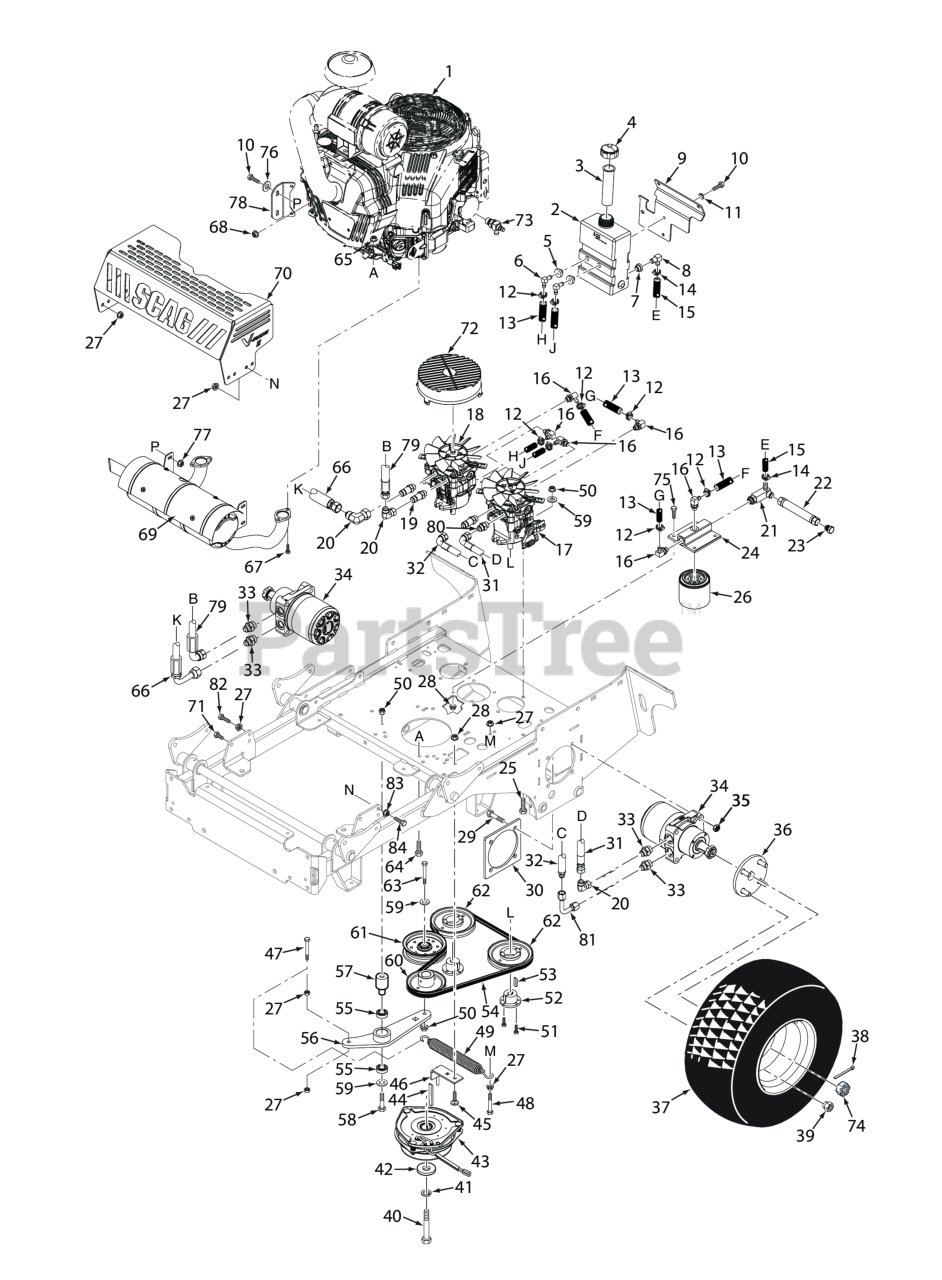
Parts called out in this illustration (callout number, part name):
1	Engine, Briggs & Stratton 37 BV-EFI (61E8770002J1)
2	Hydro Tank Assy., SVRII
3	Insert, Filler Neck
4	CAP, HYDRAULIC TANK
5	Bushing, 0.56" Dia. Viton
6	Elbow, 90 Degree, 9/16-18 JIC x 9/16 O-Ring
7	Bushing, 0.78" Dia. Viton
8	Fitting, 90 Degree - 1/2" Hose
9	Bracket, Hydro Tank Mounting
10	BOLT, SERRATED FLANGE HEX HEAD 5/16-18 X 3/4"
11	Lockwasher, 5/16 (.317 x .586 x .078) Helical Spring
12	Clamp, .69" Max. / .25" Min. Dia.
13	Hose, 3/8" ID - 10-1/4" Long (Order By The Inch)
14	Clamp, Cable 3/4" I.D.
15	Hose Assembly, 1/2" ID (Oil Reservoir to Filter Base)
16	Elbow, 90 Degree - 9/16" O-Ring x 3/8" Hose
17	Pump, LH - SVRII
18	Pump, RH - SVRII
19	Union, O-Ring to JIC
20	Elbow, 1/2 JIC Female to 1/2 JIC Male
21	Tee, 3/4" O-Ring
22	Drain, Hose Assembly
23	Plug, JIC 3/4-16 UNF
24	Filter Head Assembly
25	Bolt, Hex Head, 3/8-16 x 1-1/2"
26	OIL FILTER, SPECIAL
27	NUT, 3/8-16 SERRATED FLANGE HEX HEAD
28	Nut, Serrated Flange 5/16-18 (Right Front Engine Mounting, Briggs and Kohler Only)
29	Bolt, Hex Hd. 1/2-13 x 2-1/2" (lower)
30	Plate Weldment, Motor Backing
31	Hose Assembly
32	Hose Assy., 18-1/2"
33	TUBE UNION, 3/4-16 JIC TO 7/8-14 "O" RING
34	Wheel Motor, Parker
35	Locknut, Hex 1/2-13 Center Lock
36	Wheel Hub Assy., SVRII
37	Wheel Assembly, 24 x 12-12 (SPZ61)
38	Pin, Cotter 9/16" x 1-1/2"
39	Wheel Nut, 1/2-20 x 13/16
40	Bolt, Hex Head 7/16-20 x 2-1/4" w/Patch (Kawasaki)
41	Lockwasher, 7/16� Spring
42	Flatwasher, 7/16-.469 x 1.75 x .25 (48, 52)
43	Clutch w/Tag GT3.5--FE05 (61)
44	Key, 1/4 x 1/4 x 3-1/2"
45	Bolt, 5/16-18 x .75 RHSN Carriage
46	ANTI-ROTATION WLMT, SVRII
47	Bolt, Hex Head 3/8-16 x 1-1/2" Grade 8 Black
48	Bolt, Hex Head 3/8-16 x 3" - 52"
49	Spring, Transmission Drive
50	HEX NUT, ELASTIC STOP LOCK, 3/8-16
51	Bolt, Hex Head 1/4-20 x 1" Grade 8 Black
52	Hub, Tapered, 15mm Bore
53	KEY, 5 MM X 5 MM X 25 MM
54	Belt, Pump Drive (37BV-EFI)
55	BEARINGS, BALL, NEUTRAL RETURN
56	Idler Arm Assy.
57	Pivot, Idler
58	Capscrew, Hex Head 3/8-16 x 3.25"
59	Flatwasher, 3/8 (.391 x .938 x .105 HD) Grade 8
60	Pulley, 4-3/4" OD - 1.125 Bore
61	Pulley, Idler 4-1/2"
62	Pulley, 5.45 OD - Tapered Bore"
63	Bolt, Hex Head 3/8-16 x 2-1/4" - 61"
64	Bolt, Hex Head, 3/8-16 x 1-1/2"
65	Nut, Flanged Top Lock 3/8-16
66	Hose Assy., 15-1/4"
67	Bolt, Hex Head M8 - 1.25 x 20
68	Nut, M6-1.0 Hex Flange
69	Muffler, Vanguard 37 EFI - SVRII
70	Heatshield, Muffler- SVRII
71	Bolt, Hex Head, 3/8-16 x 3/4"
72	Fan Cover, Pump
73	Oil Drain, 35BV & 37BV-EFI - Briggs & Stratton
74	Nut, Hex Castle 1.0-20 UNEF
75	Bolt, Heax Head 5/16-18 x 1" (48V / 52V)
76	Flatwasher, 5/16-.375 x .875 x .083 (35BV & 37BV-EFI)
77	Nut, Flange Head Elastic Stop 5/16-18
78	Bracket, Muffler Mount
79	Hose Assy., 27-1/2"
80	Union, 3/4"-16 JIC x 3/4"-16 O-Ring
81	Tube Assy.
82	Bolt, Hex Head 3/8-16 x 1-1/2" Grade 8 Black
83	NUT, 3/8-16 SERRATED FLANGE HEX HEAD
84	Bolt, Hex Head, 3/8-16 x 3/4"
